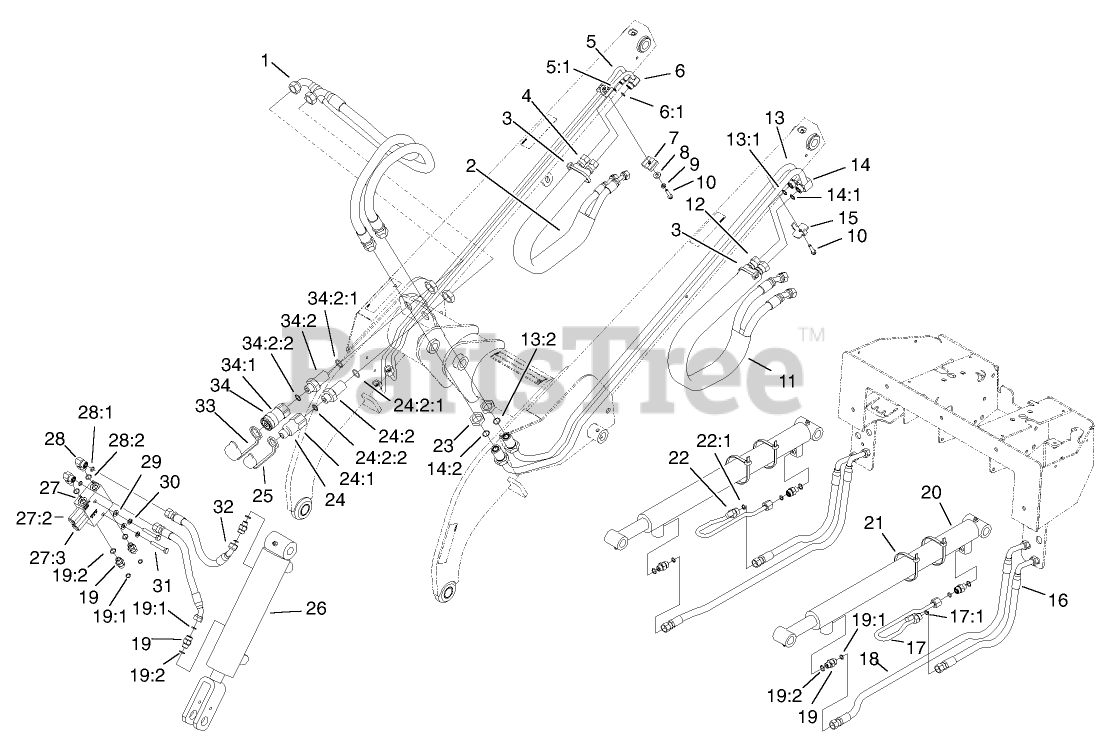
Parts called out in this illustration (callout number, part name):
1	HOSE ASM
2	SLEEVE-PROTECTIVE
3	TIE-CABLE
4	HOSE-HYD
5	HYD TUBE ASM
5:1	O-RING
6	HYD TUBE ASM
6:1	O-RING
7	CLAMP-TUBE
8	WASHER-FLAT
9	WASHER-LOCK
10	SCREW-HWH
11	SLEEVE-PROTECTIVE
12	HOSE-HYD
13	HYD TUBE ASM
13:1	O-RING
13:2	O-RING
14	HYD TUBE ASM
14:1	O-RING
14:2	O-RING
15	PLATE-CLAMP, TUBE
16	HOSE-HYD
17	HYD TUBE ASM
17:1	O-RING
18	HYD HOSE ASM
19	FITTING-STRAIGHT
19:1	O-RING
19:2	O-RING
20	CYLINDER-LIFT
21	TIE-CABLE
22	HYD TUBE ASM
22:1	O-RING
23	NUT-LOCK, BULKHEAD
24	BULKHEAD NIPPLE ASM
24:1	NIPPLE-FACE, FLUSH
24:2	FITTING-ADAPTER, BULKHEAD
24:2:1	O-RING
24:2:2	O-RING
25	CAP-DUST, NIPPLE
26	CYLINDER-TILT
27	VALVE-RELIEF, CROSSOVER
27:1	SEAL KIT
27:2	CARTRIDGE-RELIEF
27:3	CARTRIDGE-RELIEF
28	FITTING-ELBOW, 90 DEG
28:1	O-RING
28:2	O-RING
29	WASHER-PLAIN
30	WASHER-LOCK
31	SCREW-HH
32	HOSE-HYD
33	CAP-DUST, COUPLER
34	BULKHEAD COUPLER ASM
34:1	COUPLER-FACE, FLUSH
34:2	FITTING-ADAPTER, BULKHEAD
34:2:1	O-RING
34:2:2	O-RING
